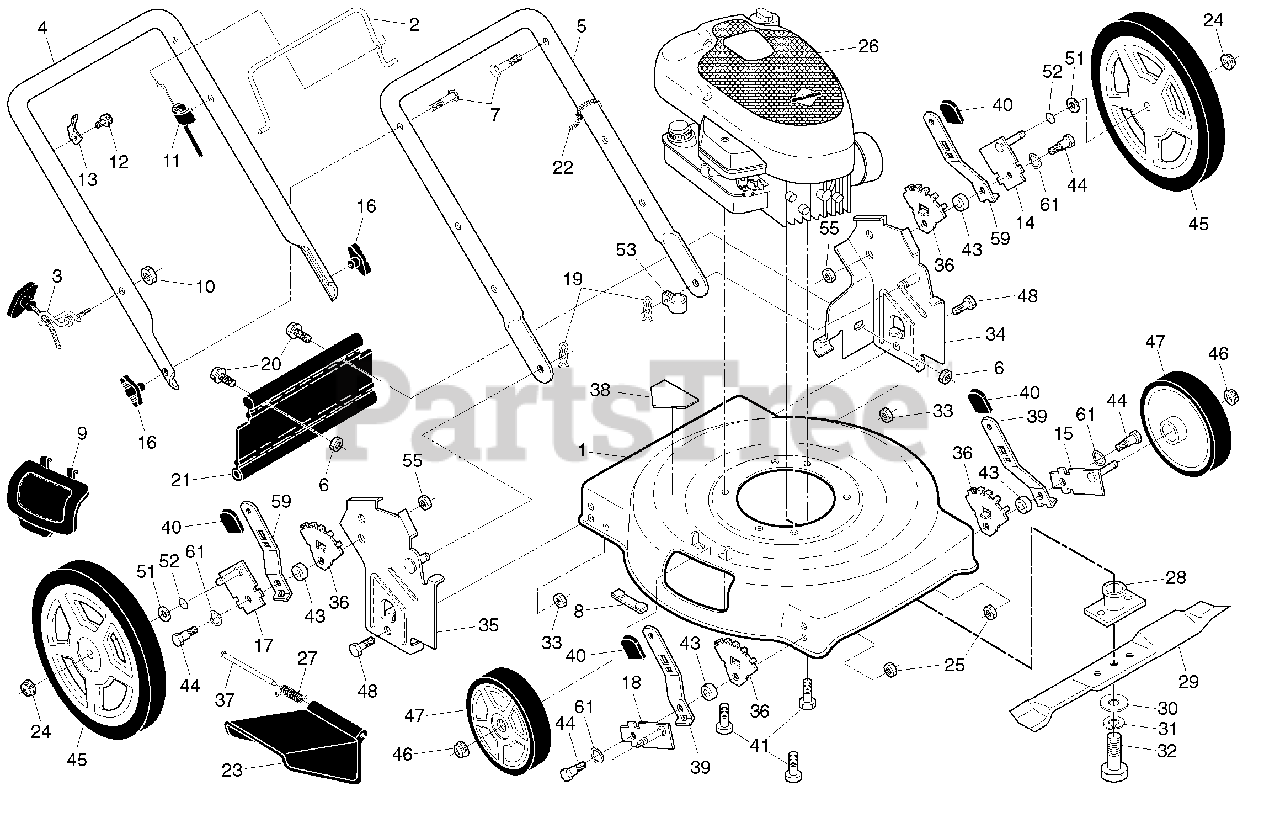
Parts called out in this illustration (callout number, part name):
1	Lawn Mower Housing
2	Control Bar
3	Rope Guide
4	Upper Handle
5	Lower Handle
6	Locknut, Hex 1/4-20
7	Handle Bolt 5/16-18
8	Clip, Closeout
9	Mulcher Plate
10	Nut, Hex 1/4-20
11	Engine Zone Control Cable
12	Hex Washer Head Screw #10-24 x 1/2
13	Up-Stop Bracket
14	Axle Arm Assembly, Rear, LH
15	Axle Arm Assembly, Front, LH
16	Handle Knob
17	Axle Arm Assembly, Rear, RH
18	Axle Arm Assembly, Front, RH
19	Hairpin Cotter
20	Screw, Hex Cap Head 1/4-20
21	Rear Deflector
22	Wire Tie
23	Discharge Guard
24	Nut, Hex, Flangelock 3/8-16
25	Nut, Hex, Flangelock 5/16-18
27	Torsion Spring
28	Blade Adapter
29	22" Blade
30	Hardened Washer
31	Helical Lockwasher 3/8
32	Screw, Hex Head, Grade 8, 3/8-24 x 1-3/8
33	Nut, Hex, Nylock 5/16-18
34	Wheel Bracket Support, LH
35	Wheel Bracket Support, RH
36	Wheel Bracket Adjuster
37	Hinge Rod
38	Danger Decal
39	Selector Spring, Front
40	Selector Knob
41	Screw, Hex Head, Threaded, Rolled 3/8-16 x 1
43	Spacer
44	Shoulder Bolt 5/16-18
45	Wheel & Tire Assembly, Rear, 12"
46	Nut, Hex, Flangelock 3/8-16
47	Wheel & Tire Assembly, Front, 7"
48	Bolt, Hex Head 5/16-18
51	Washer, Flat 3/8
52	O-Ring
53	Clip, Cable
55	Nut, Hex
59	Selector Spring, Rear
61	Washer, Curved, Cylindrical
61	Operator's Manual, English
61	Operator's Manual, French
61	Repair Parts Manual
